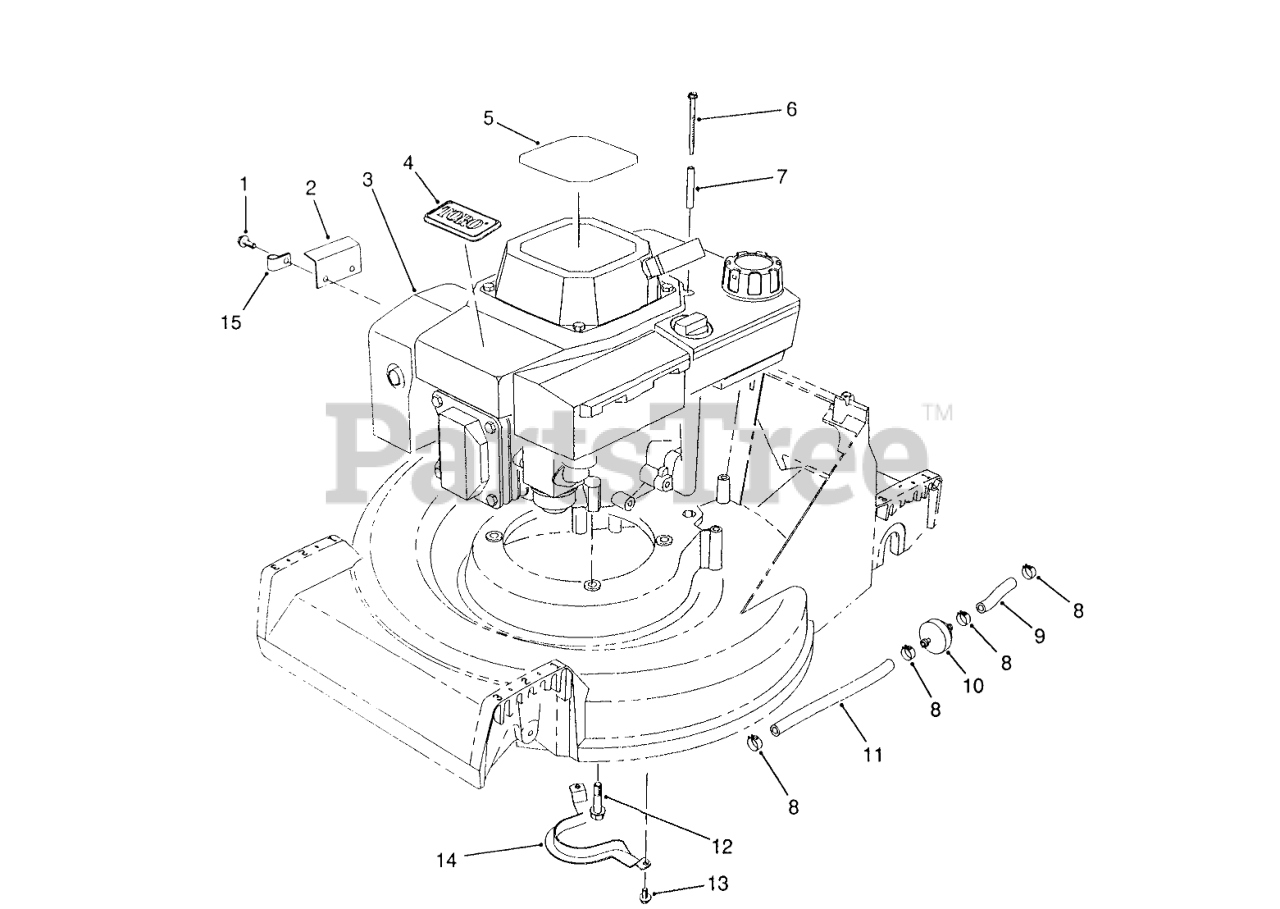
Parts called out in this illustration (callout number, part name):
1	THO FORM SCREW M6 X 1
2	FLYWHEEL SHIELD
3	Engine-OHV
4	TORO LOGO PLT
5	DECAL-HV INT'L
6	THRD FORMING SCREW
7	TUBULAR SPACER
8	CLAMP-FUEL LINE
9	LINE-GAS
10	FILTER-FUEL
11	HOSE-FUEL
12	SCREW-HWHTF
13	SCREW-HWHTF
14	Guide-Belt
15	CLAMP-R
